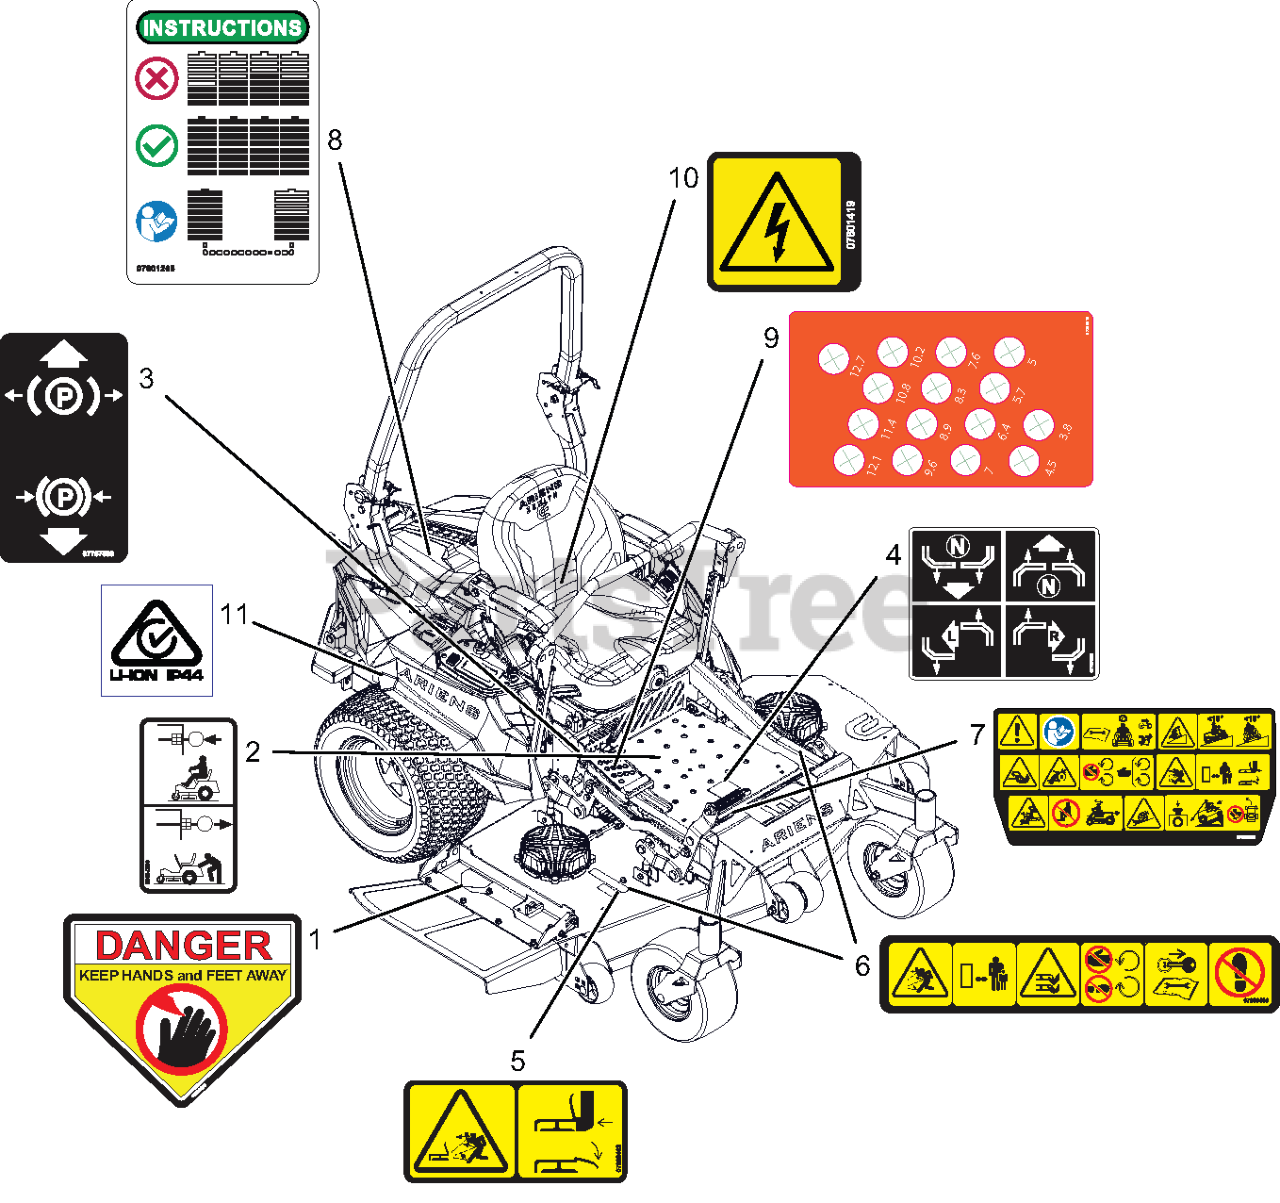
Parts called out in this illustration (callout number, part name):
1	DECAL, DANGER
2	DECAL, TRANSMISSION DISCONNECT
3	DECAL, PARKING BRAKE LEVER
4	DECAL, INSTRUCTIONAL-STEERING
5	DECAL, SAFETY - DECK GUARDING
6	DECAL, DECK SAFETY
7	DECAL, MAIN SAFETY
8	DECAL, BATTERY BALANCE
9	DECAL, APEX HOC METRIC
10	DECAL, SAFETY - DANGER
11	DECAL, LI-ION IP44
